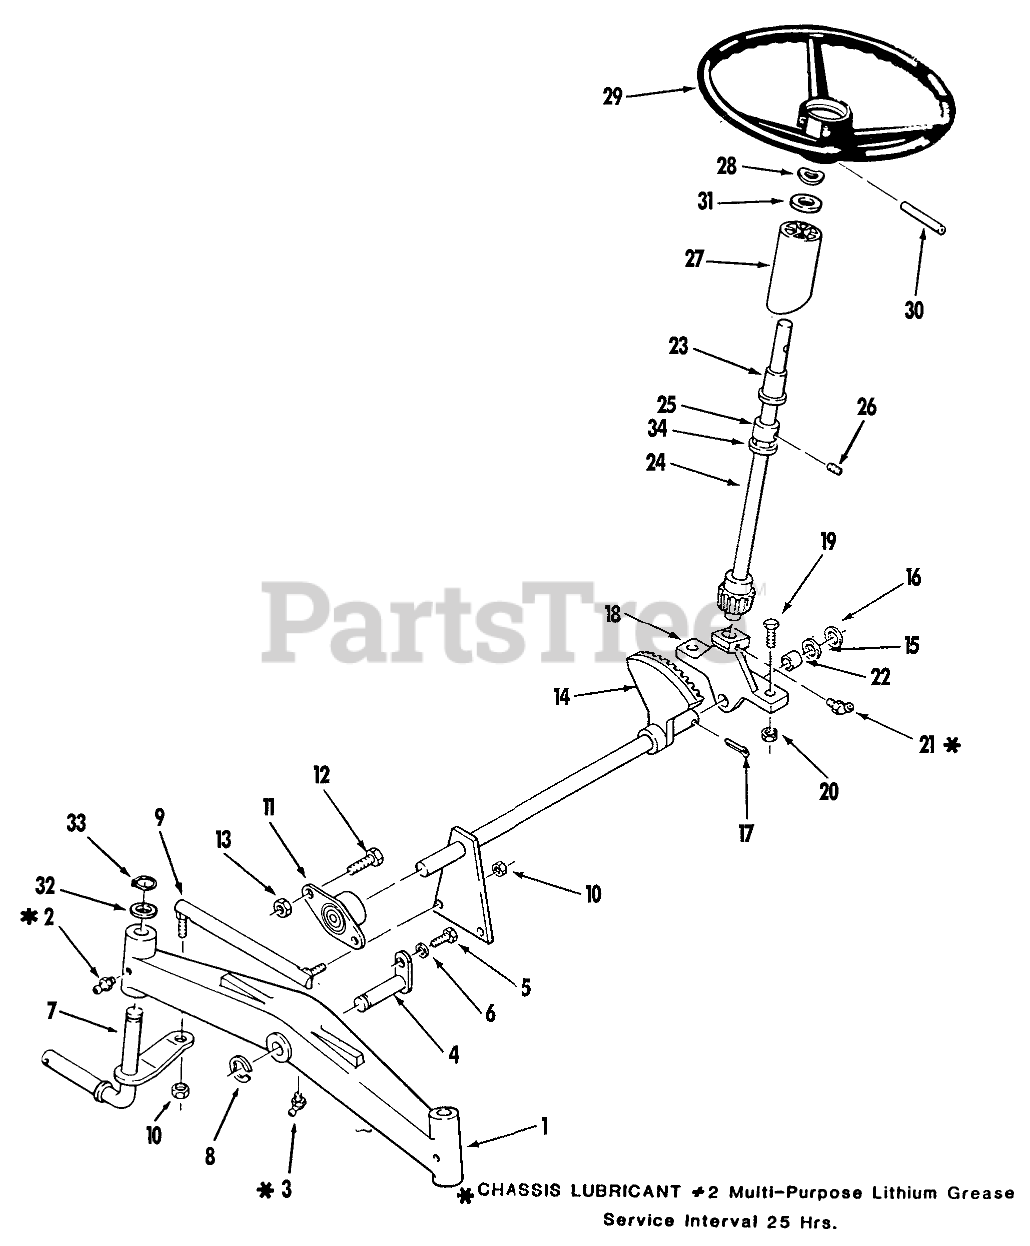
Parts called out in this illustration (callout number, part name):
1	AXLE-FRONT
2	Zerk
3	FITTING-GREASE
4	PIN AND PLATE ASM
5	SPINDLE ASSY RH W/O R
6	SPINDLE ASM LH W/O R
7	SPINDLE ASSY RH W/O R
8	E-RING
9	Tie Rod RH
10	Nut
11	BEARING-FLANGED
12	BOLT
13	NUT
14	ASS'Y-STRG SHAFT R
15	WASHER-SHIM
16	WASHER
17	PIN-4
18	Support
19	Bolt
20	NUT
21	FITTING-GREASE
22	BEARING-BRONZE
23	BEARING-FLANGED
24	Shaft-Upper Steering
25	Collar
26	SCREW-SET
27	TUBE-STEERING
28	WASHER-BOWED
29	Steering Wheel
30	Pin-Roll
31	WASHER-FLAT
32	WASHER
33	Snap Ring
34	RING-RETAINING
